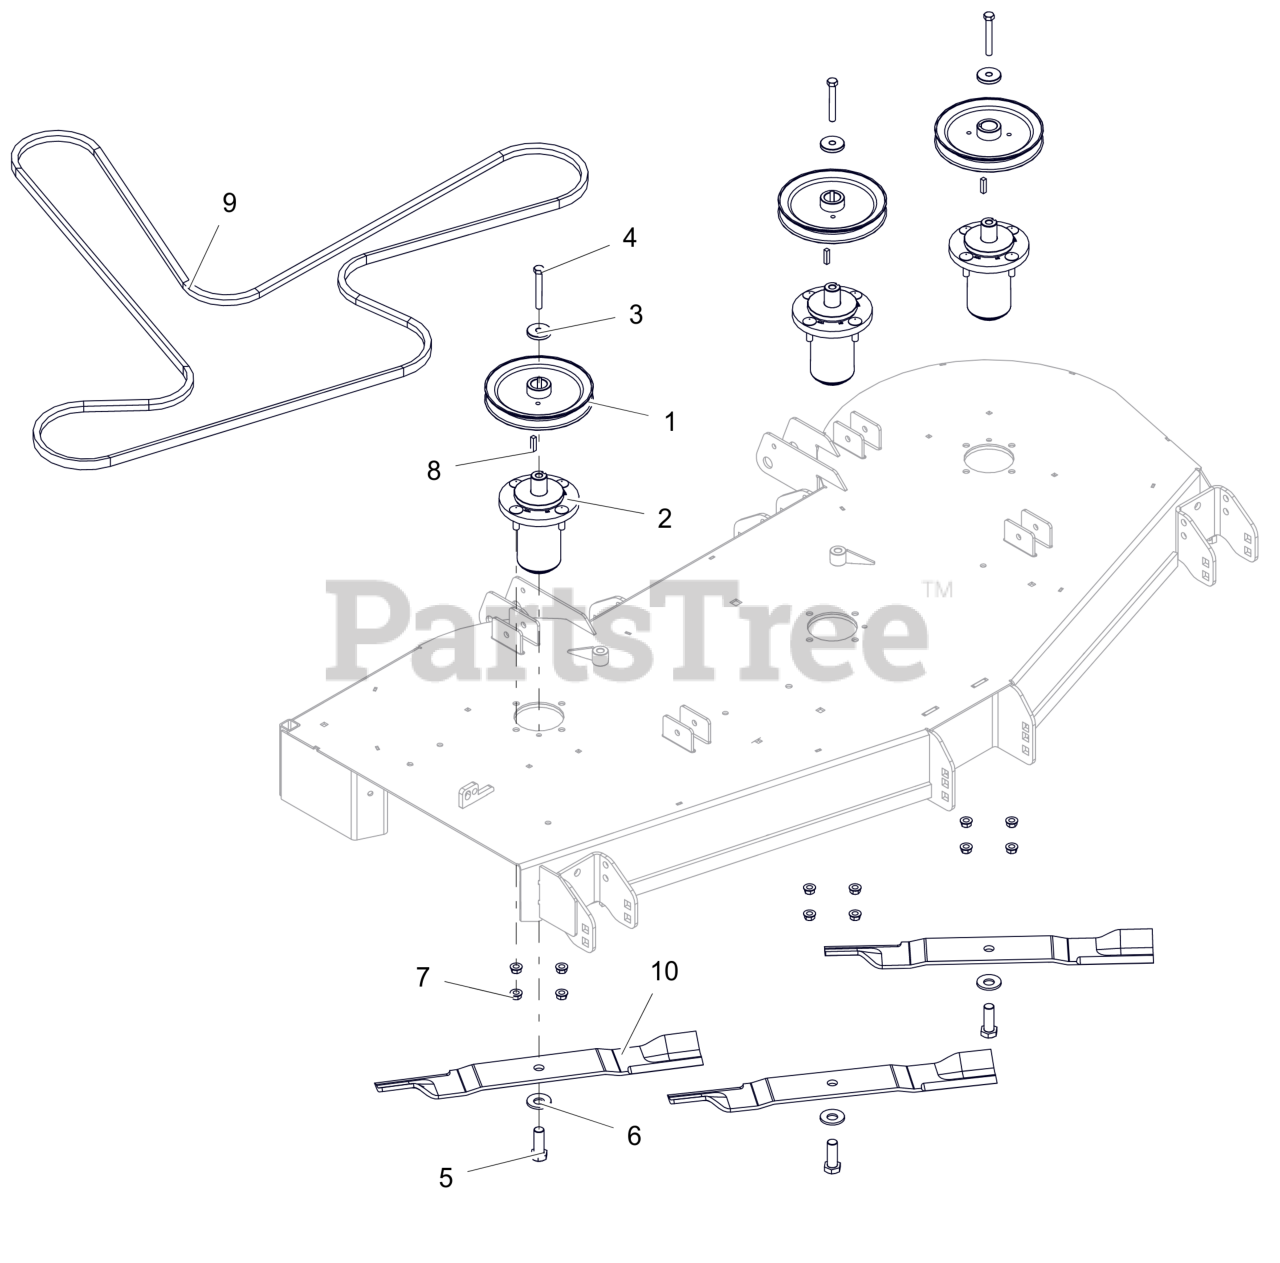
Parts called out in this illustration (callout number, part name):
1	PULLEY, V-1.00 ID X 6.75 OD
2	ASM, MAINT FREE ALUM SPINDLE
3	RETAINER, SHEAVE
4	BLT, HEX .38-16X2.75 G8 ZCC
5	BLT, HEX .62-18X1.75 G8 ZCC
6	WSHR-BLVL .669X1.535X.138
7	NUT-LK-CTR-FLG .375-16 GF ZCC
8	KEY, SQ .25X.25X1.00 RC 40-50
9	BELT, V, RAW EDGE EPDM
10	BLADE, MOWER (20.50")
